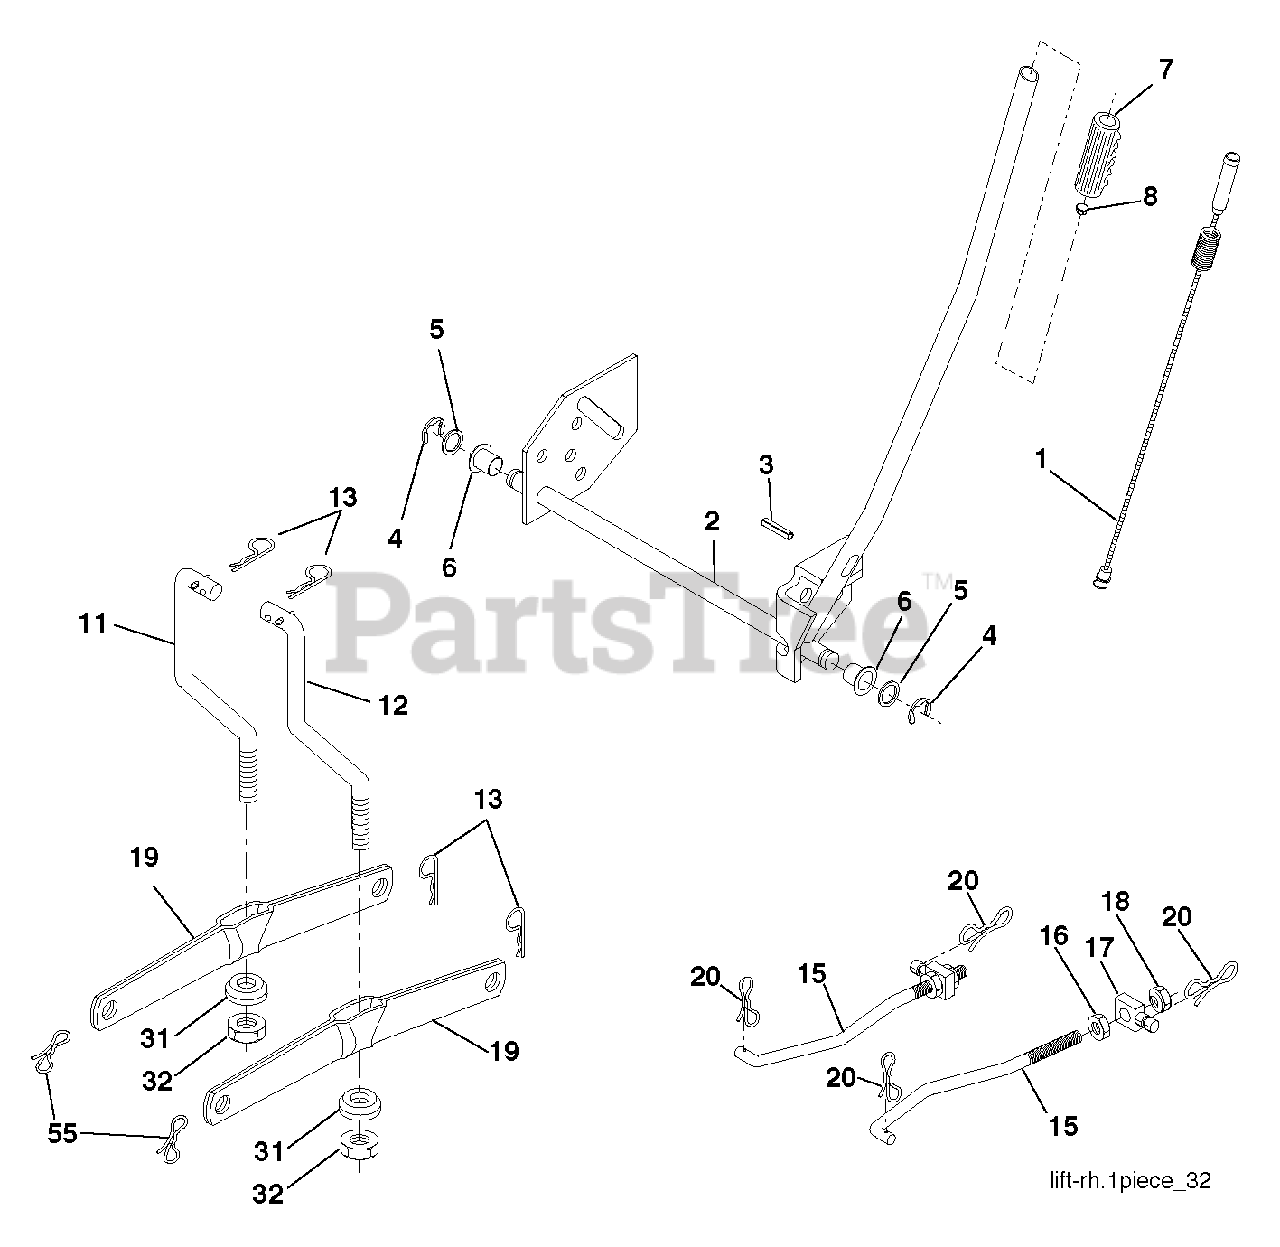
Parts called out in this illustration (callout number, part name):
1	PLUNGER.ASM.LIFT.LEVER.BLK.
2	SHAFT.ASM.LIFT.YT
3	PIN.GROOVE.5/16
4	RETAINING RING LT
6	BEARING.NYLON
7	GRIP HANDLE
8	PLUNGER BUT KIT
11	LINK LIFT LH
12	Lift Link Assembly, RH
13	RETAINER-SPRNG RB
15	LINK.SUSPENSION.FRONT
16	NUT.HEX.JAM.1/2-13
17	TRUNNION
18	NUT.LK.W/WSH.1/2.
19	ARM.REAR.SUSPENSION
20	PIN.COTTER.7/16.BOW TI.
31	BEARING.PIVOT.LIFT
32	NUT CROWNLOCK 3/8-24
55	PIN.COTTER.5/16.BOW TI
